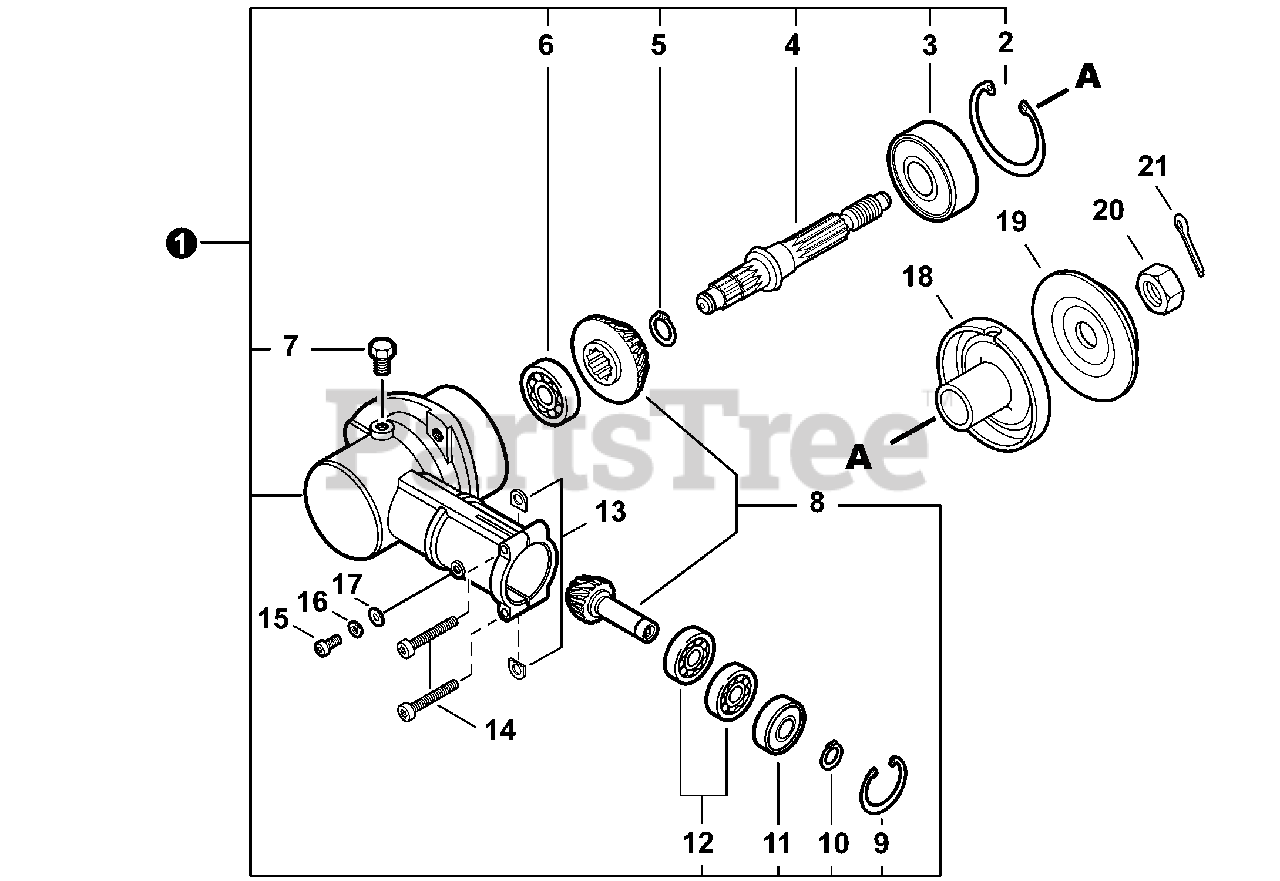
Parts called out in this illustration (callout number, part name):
1	GEAR CASE ASSY
2	RING, SNAP Ø42
3	BEARING, BALL 6302
4	SHAFT, GEAR
5	RING, SNAP Ø12
6	BEARING, BALL 629
7	BOLT M8×8
8	GEAR SET
9	RING, SNAP Ø22
10	RING, SNAP Ø10
11	BEARING, BALL 6900Z
12	BEARING, BALL 6900
14	BOLT, TORX 5×25
15	BOLT, TORX 5×12
16	WASHER, SPRING 5
17	WASHER, FLAT 5.5×10×0.8
18	PLATE, ADAPTOR - UPPER
19	PLATE, ADAPTOR - LOWER
20	NUT 10×1.25 LH
21	PIN, COTTER 2×22
